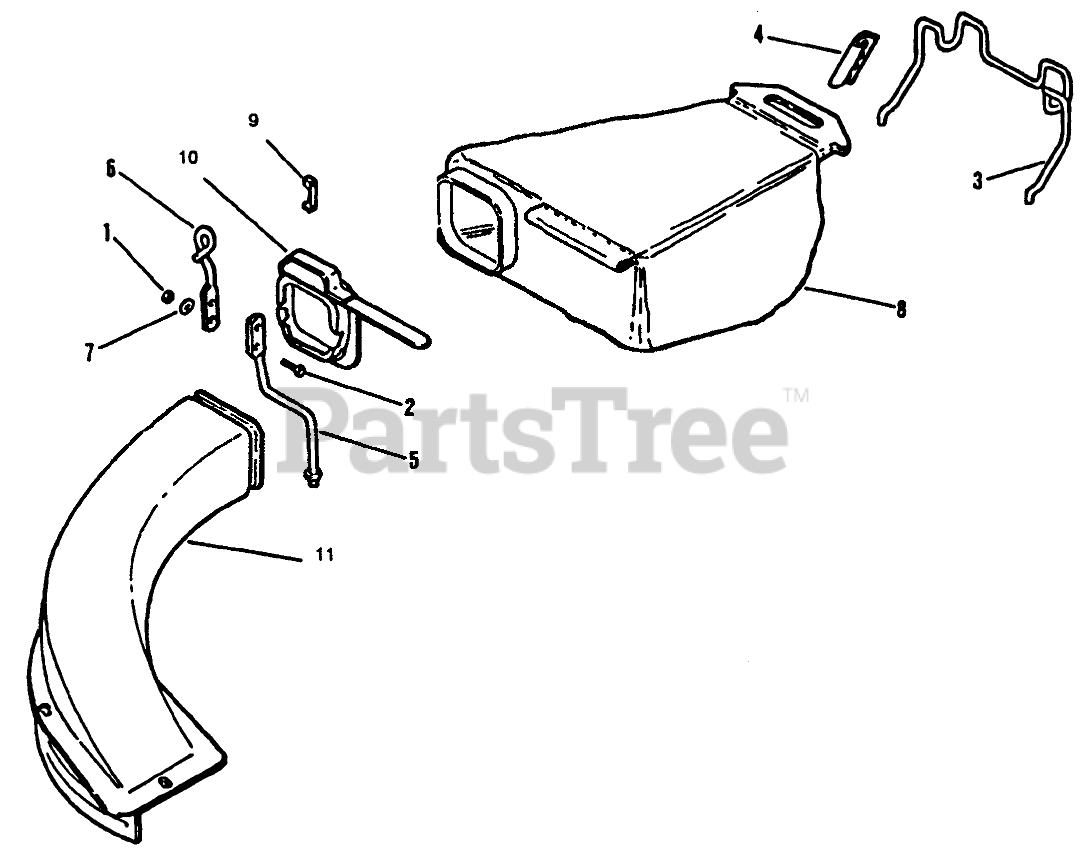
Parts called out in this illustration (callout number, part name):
1	LOCKNUT E
2	SCREW OBS
3	HANGER-WIRE
4	Bracket
5	SUPP0RT CHUTE ARGO
6	GUIDE ROPE ARGO
7	WASHER BADGER
8	Bag Assembly
9	Strap
10	Adaptor Assembly
11	REAR CATCHR CHUTE
